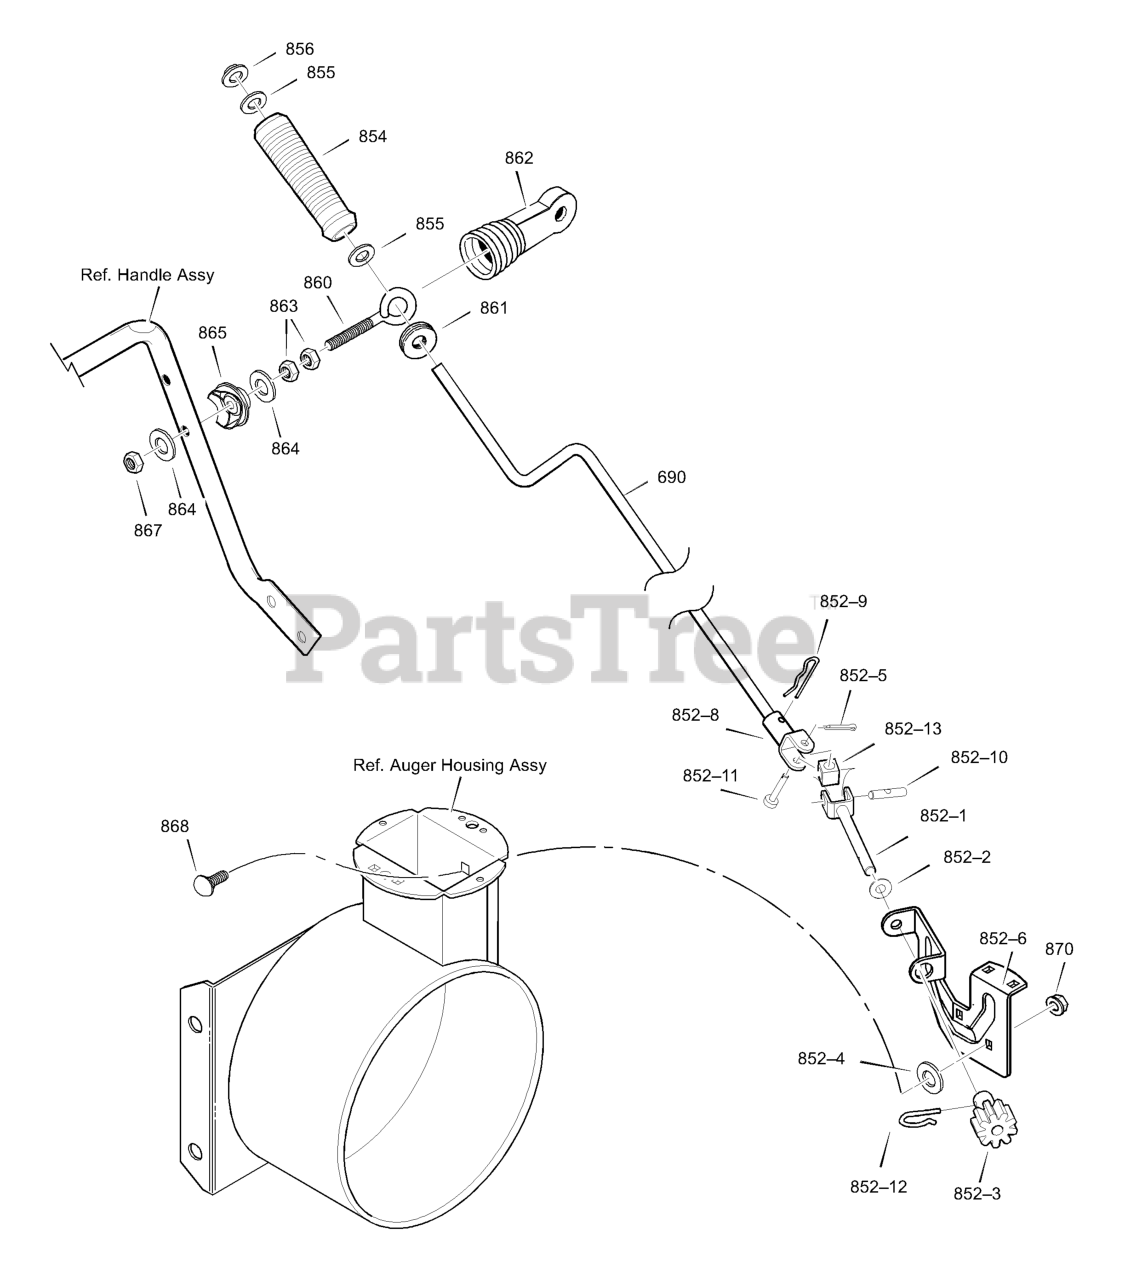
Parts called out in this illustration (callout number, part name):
852-1	ASSEMBLY, YOKE & ROD
852-2	WASHER, CURVED SPRING
852-3	GEAR, CHUTE ROTATION 9T
852-4	FLATWASHER
852-5	PIN, COTTER
852-6	BRACKET, GEAR MOUNT
852-8	ASSEMBLY, YOKE ADAPTER YZ
852-9	PIN, HAIR
852-10	PIN, UNIVERSAL JOINT
852-11	PIN, CLEVIS
852-12	PIN, COTTER
852-13	HOUSING, UNIVERSAL
854	KNOB, SLEEVE
855	FLATWASHER
856	NUT, PUSH ON 3/8"
860	EYE BOLT 3/8-16X6.00
861	GROMMET, EYE BOLT
862	BOOT, EYE BOLT
863	NUT, 3/8-16 HEXJAM
864	FLATWASHER .406X.81X.066
865	ADAPTER, BOOT
867	NUT, 3/8-16 HEXNYL
868	BOLT, CARRIAGE 1/4-20 X 1.00
869	CRANK, ASSY CHUTE
870	NUT
